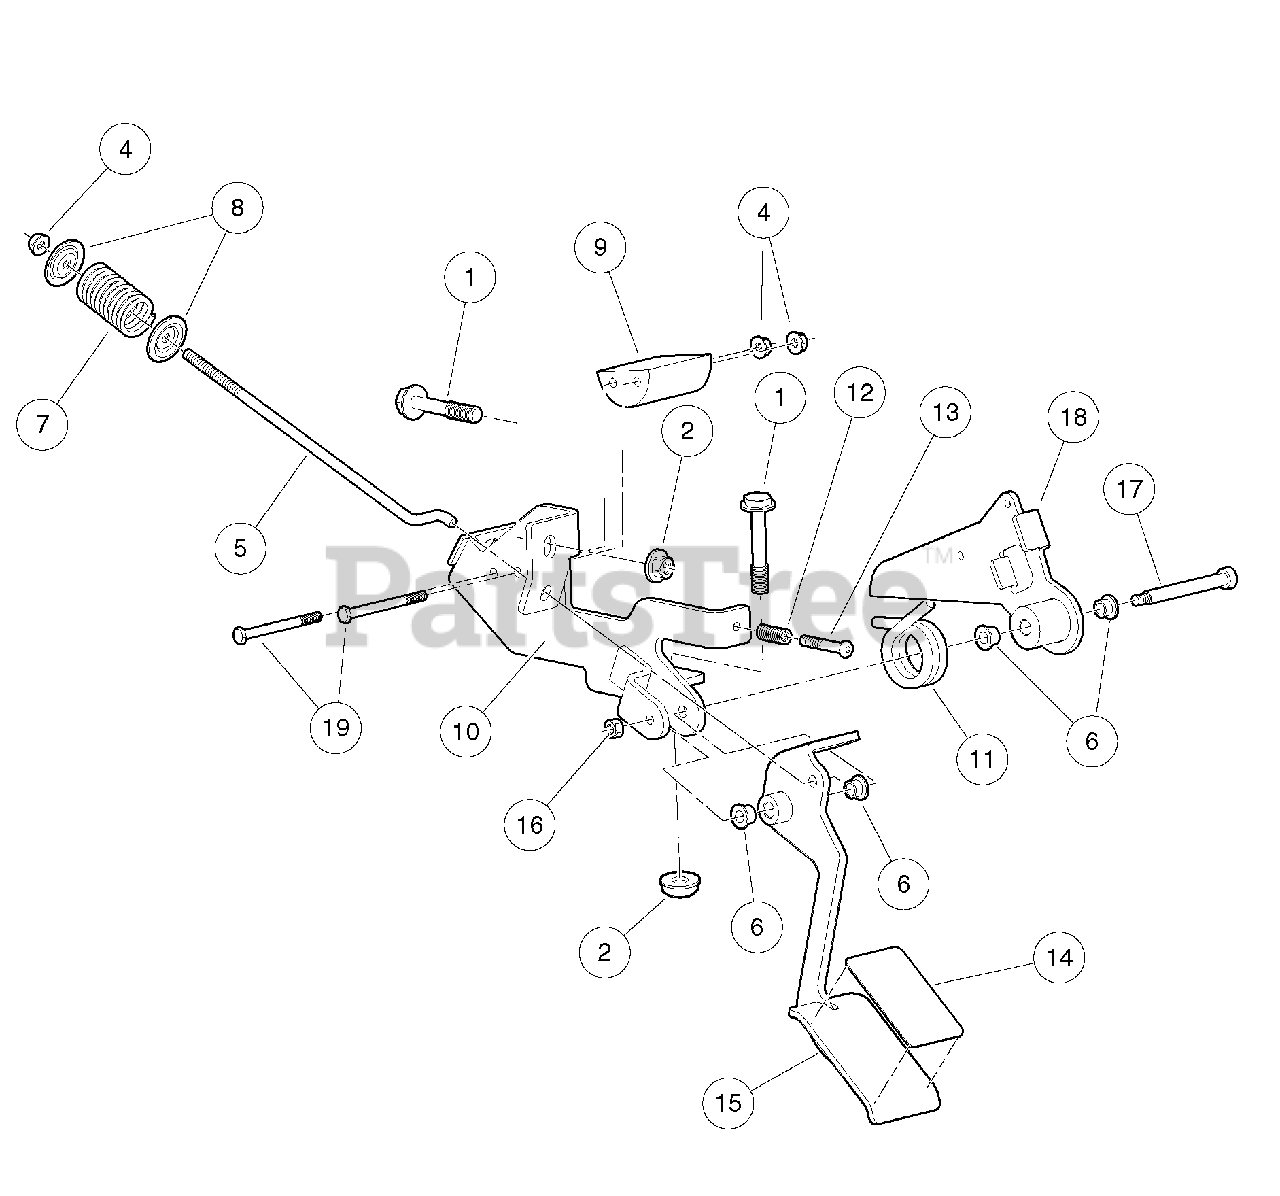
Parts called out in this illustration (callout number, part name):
1	Bolt Flanged Head, M8 X 1.25 X 65
2	Lock Nut, Flg M8 X 1.25 Nylon
3	Asm, Accelerator Pedal
4	Nut-m6x1.0 Flng All Mtl Lock
5	Pullrod, Spring, Compression
6	Bushing, Greaseless
7	Spring, Comp, Pedal, Pullrod
8	Washer, Retaining Spring, 7mm
9	Guide, Cable, Accelerator
10	Weldment, Bracket, Pedal
11	Spring, Torsion
12	Spring, Stop, Pedal
13	Bolt, Stop, Pedal
14	Pad, Grip Tape, Accelerator
15	Weldment, Pedal, Accelerator
16	Nut M6x1 Mech Def Center
17	Bolt, Shoulder, M8 X 70, Hc
18	Weldment, Lever, Lost Motion
19	Bolt, M6 X 1 X 70
